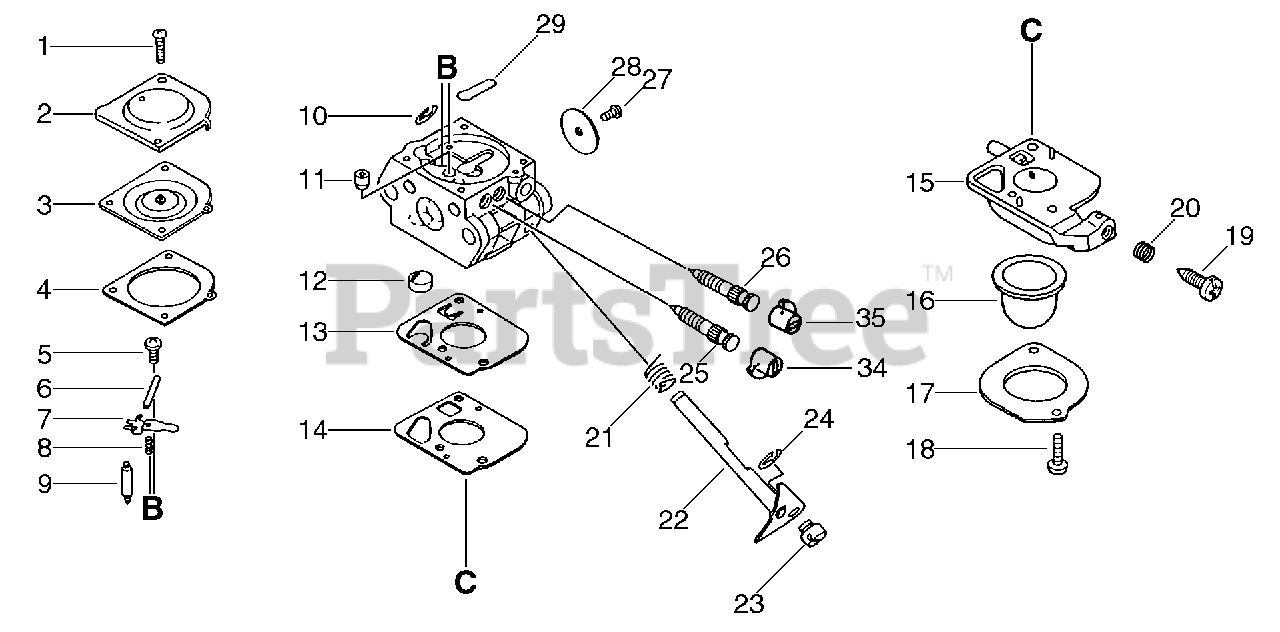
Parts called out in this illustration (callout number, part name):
2	COVER, METERING
3	DIAPHRAGM, METERING
4	GASKET, DIAPHRAGM
5	SCREW, METERING LEVER PIN
6	PIN, METERING LEVER
7	LEVER, METERING
9	VALVE, INLET NEEDLE
10	RING, RETAINING
11	NOZZLE, CHECK VALVE
12	STRAINER
13	DIAPHRAGM, PUMP
14	GASKET, PUMP
15	PRIMER BASE ASSY
16	BULB, PURGE
17	RETAINER, PURGE BULB
18	SCREW, RETAINER
19	SCREW, IDLE ADJUST
20	SPRING, IDLE ADJUST
21	SPRING, RETURN
22	SHAFT, THROTTLE
24	RING, RETAINING
25	NEEDLE - HIGH SPEED
26	NEEDLE - LOW SPEED
28	VALVE, THROTTLE
29	REPAIR KIT
34	CAP, LIMITER
35	CAP, LIMITER
